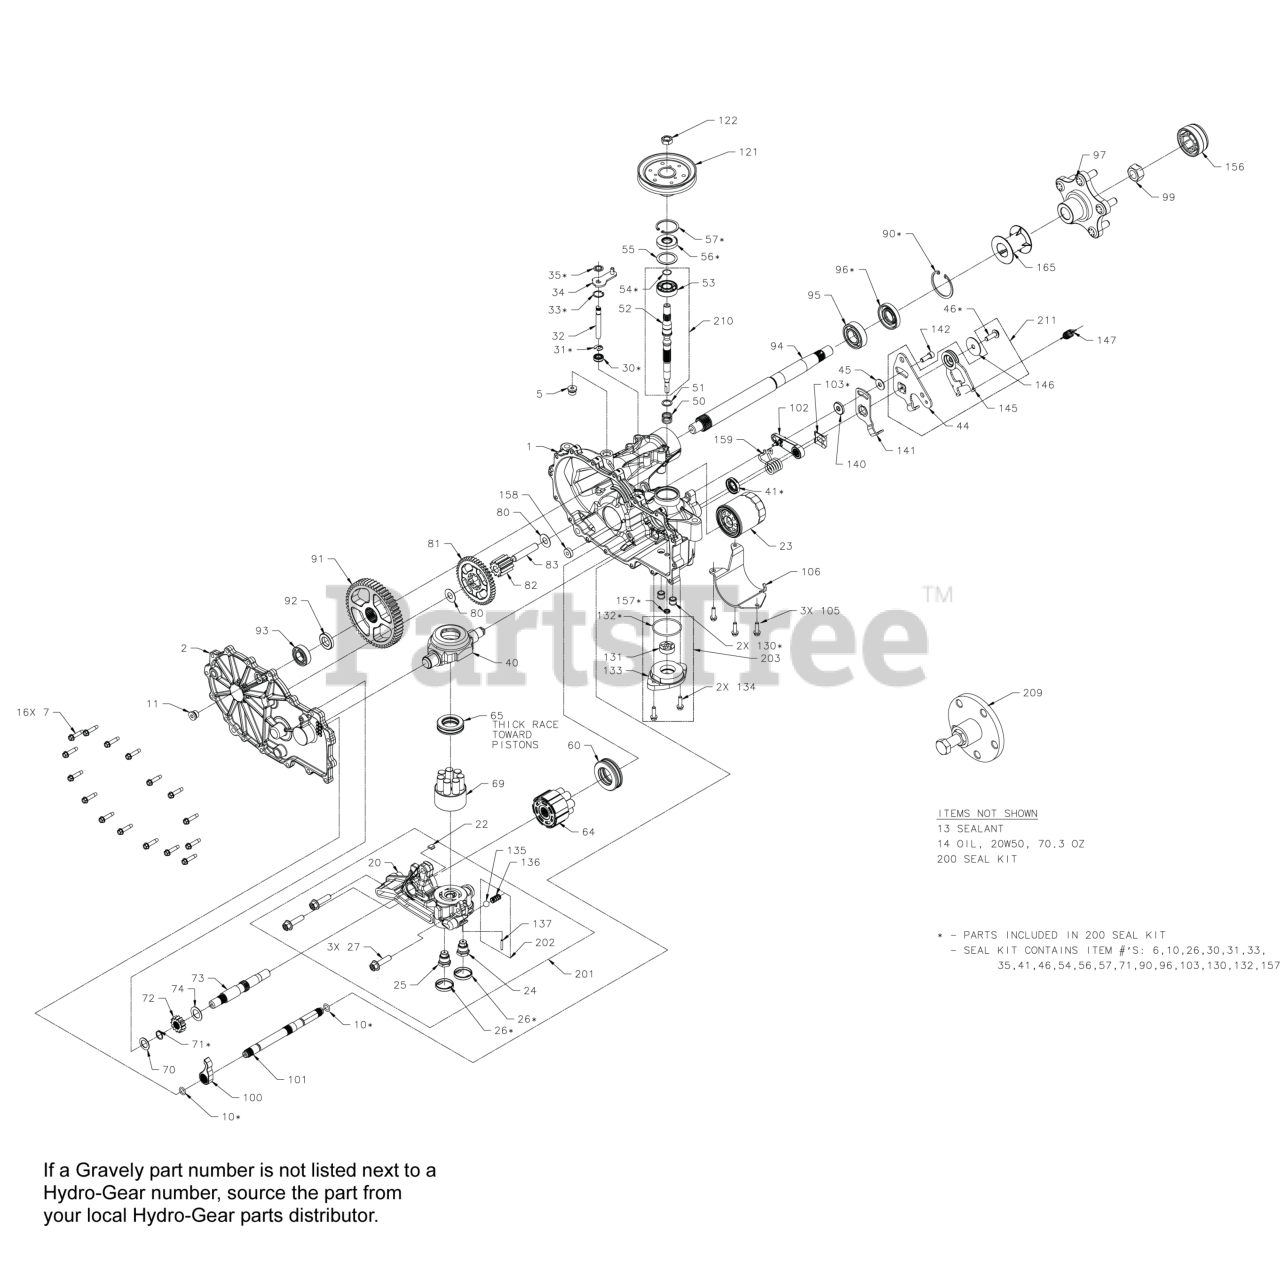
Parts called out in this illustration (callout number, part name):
1	KIT, HOUSING,MAIN,LH,CHRG,CNTL
2	KIT, COVER, SIDE, LH
5	PLUG, 9/16 18 METAL
7	SCREW,HEX WASHER 1/4-20X1.125
11	PLUG, 9/16 18 METAL
13	SEALANT TUBE 10.1OZ.
14	FLUID, HYDRO 15W50 QT
14	FLUID, HYDRO 20W50 QT
22	PLATE, BYPASS
23	FILTER, HYDRO-GEAR 2800 TRANS
26	SEAL, PLUG 1.375 X .250
27	HFHCS 3/8-16X1.5 (PATCH)
30	SEAL, LIP .375X.75X.25
31	RING. RETAINING
32	ROD, BYPASS
33	RING, RET .750
34	HG BYPASS ARM (52370)
35	RING, RTNG .
40	TRUNNION, SWASHPLATE
46	TWHCS 5/16-24 X 1.00
50	SPRING. BLOCK
51	WASHER. THRUST .59 X .79 X .04
55	WASHER 1.23X1.56X.04
57	RING, RET 1.56 INT
60	HG THRUST BEARING (51462)
64	HG 16CC CYLINDER BLOCK (71579)
65	HG THRUST BLOCK (53502)
69	HG SEVEN PISTON BLOCK (71971)
70	WASHER .63X1.0X.05
71	RING, RET 62 EXT
72	GEAR, 13T, STEEL
73	SHAFT, MOTOR
74	WASHER .71 X 1.16 X .04
80	WASHER .5X1.0X.032
82	GEAR 11 TOOTH STEEL
83	JACK SHAFT (PIN)
90	RING, RETAINING
91	GEAR, 54T
94	SHAFT, AXLE
97	HUB, HYDROGEAR P/N 71691
100	PAWL, BRAKE
101	SHAFT, BRAKE
102	KIT HANDLE, ACTUATING
103	CLIP, RETAINING
106	GUARD, FILTER, LH
121	PULLEY, 4.5 INCH
122	NUT, HEX 1/2-20 PATCH
130	TUBE, CONNECTING
132	O-RING HYDROGEAR 52250
133	COVER, CHARGE PUMP
141	ARM, NEUTRAL LEFT
142	SHCS 5/16-24X1 PATCH
147	SPRING, HYDROGEAR P/N 51833
157	SEAL, LIP 8 X 12 X 3 VC
158	MAGNET, RING
159	SPRING, TORSION, CW
165	TUBE, AXLE 2.03
200	KIT, SEAL
201	HG CENTER SECTION KIT (71973)
202	KIT CHARGE RELIEF
203	KIT, CHARGE PUMP
209	HUB PULLER 5 BLT
210	INPUT SHAFT HG 71978
211	TRN KIT HRDROGEAR P/N 71599
